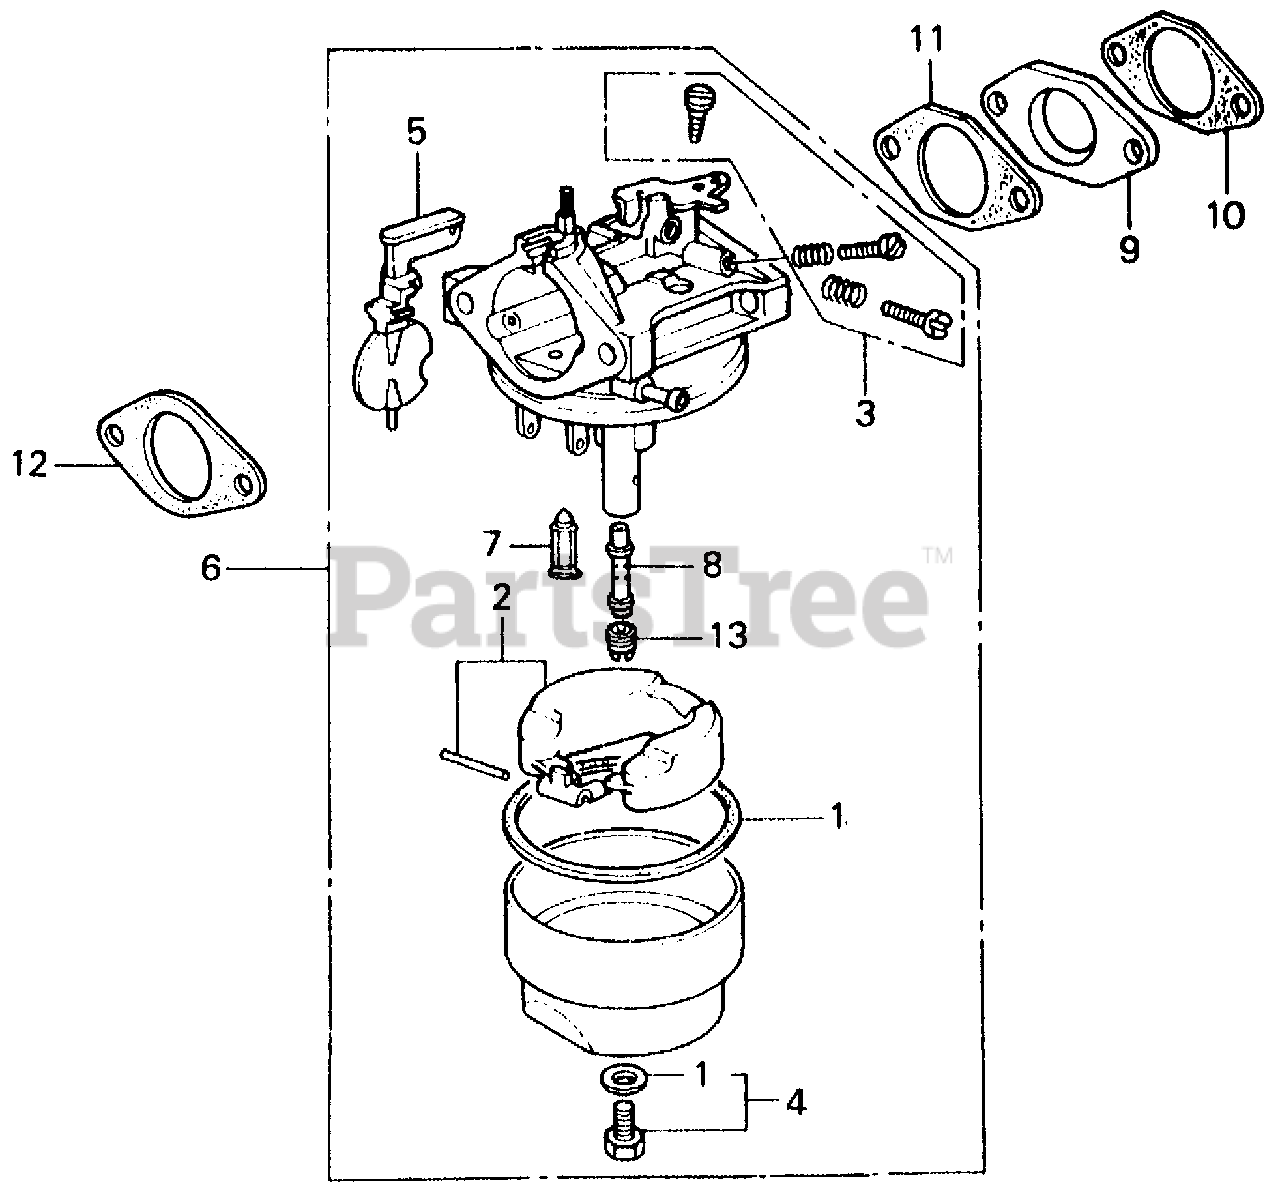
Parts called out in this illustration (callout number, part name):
1	GASKET SET
2	FLOAT SET
3	SCREW SET A
4	SCREW SET B
5	CHOKE SET
6	CARBURETOR ASSY.
6	CARBURETOR ASSY. (BB30C A)
7	VALVE, FLOAT
8	NOZZLE, MAIN
9	INSULATOR, CARBURETOR
10	GASKET, INSULATOR
11	GASKET, CARBURETOR
12	GASKET, AIR CLEANER
13	JET, MAIN (#65) Use from Engine SN BB30C A.
13	JET, MAIN (#68) Use from Engine SN BB30C A.
13	JET, MAIN (#70) Use from Engine SN BB30C A.
13	JET, MAIN (#72)
